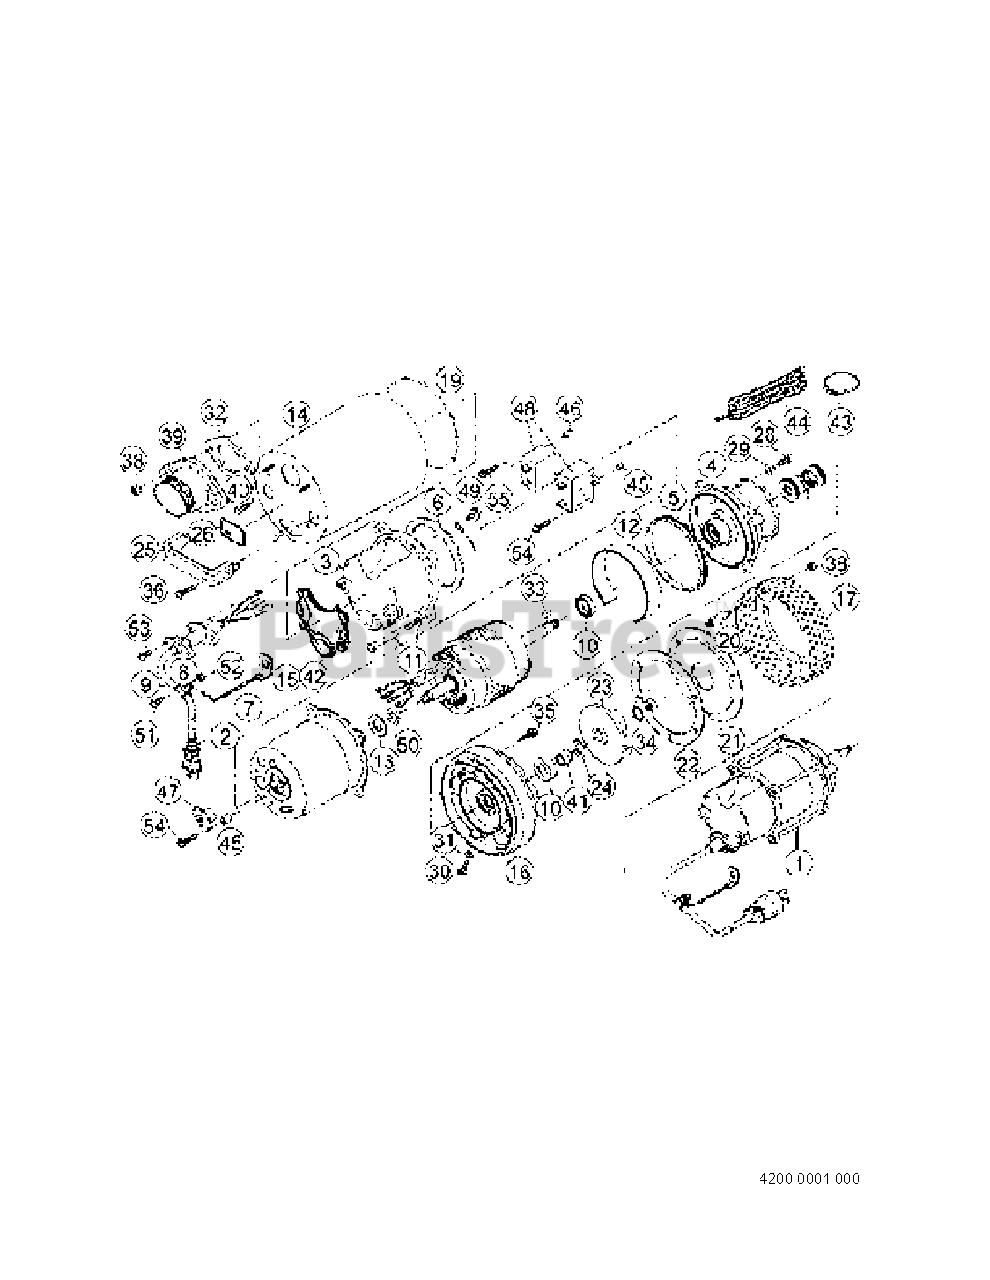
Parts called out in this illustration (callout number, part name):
2	POWER CORD
3	HEAD COVER
4	FRONT BRACKET
5	FRAME GASKET
6	HEAD GASKET
7	CHAIN AY
8	CORD BAND
9	CORD SUPPORTER
10	OIL SEAL
11	SCREW
12	SUPPORTER
13	WASHER
14	OUTER COVER
15	OUTER GASKET
16	CASING
17	STRAINER
18	O RING
19	O RING
20	STUD BOLT
21	SUCTION COVER
22	SUCTION COVER GASKET
23	IMPELLER
24	ADJUSTING WASHER
25	HANDLE
26	LABEL
27	MECHANICAL SEAL
28	SCREW
29	SEAL RING
30	HEX SOCKET BOLT
31	SEAL WASHER
32	DELIVERY GASKET
34	TOOTHED WASHER
35	HEX SOCKET BOLT
36	SCREW
37	NUT
38	NUT
39	DELIVERY FLANGE
40	HEX BOLT
41	SLEEVE
43	HOSE BAND
44	ROPE
45	SPACER
46	SPACER
47	THERMAL PROTECTOR
48	CONDENSER
49	SCREW
50	WAVE WASHER
51	SCREW
52	HEX NUT
53	SCREW
54	SCREW
55	SCREW
